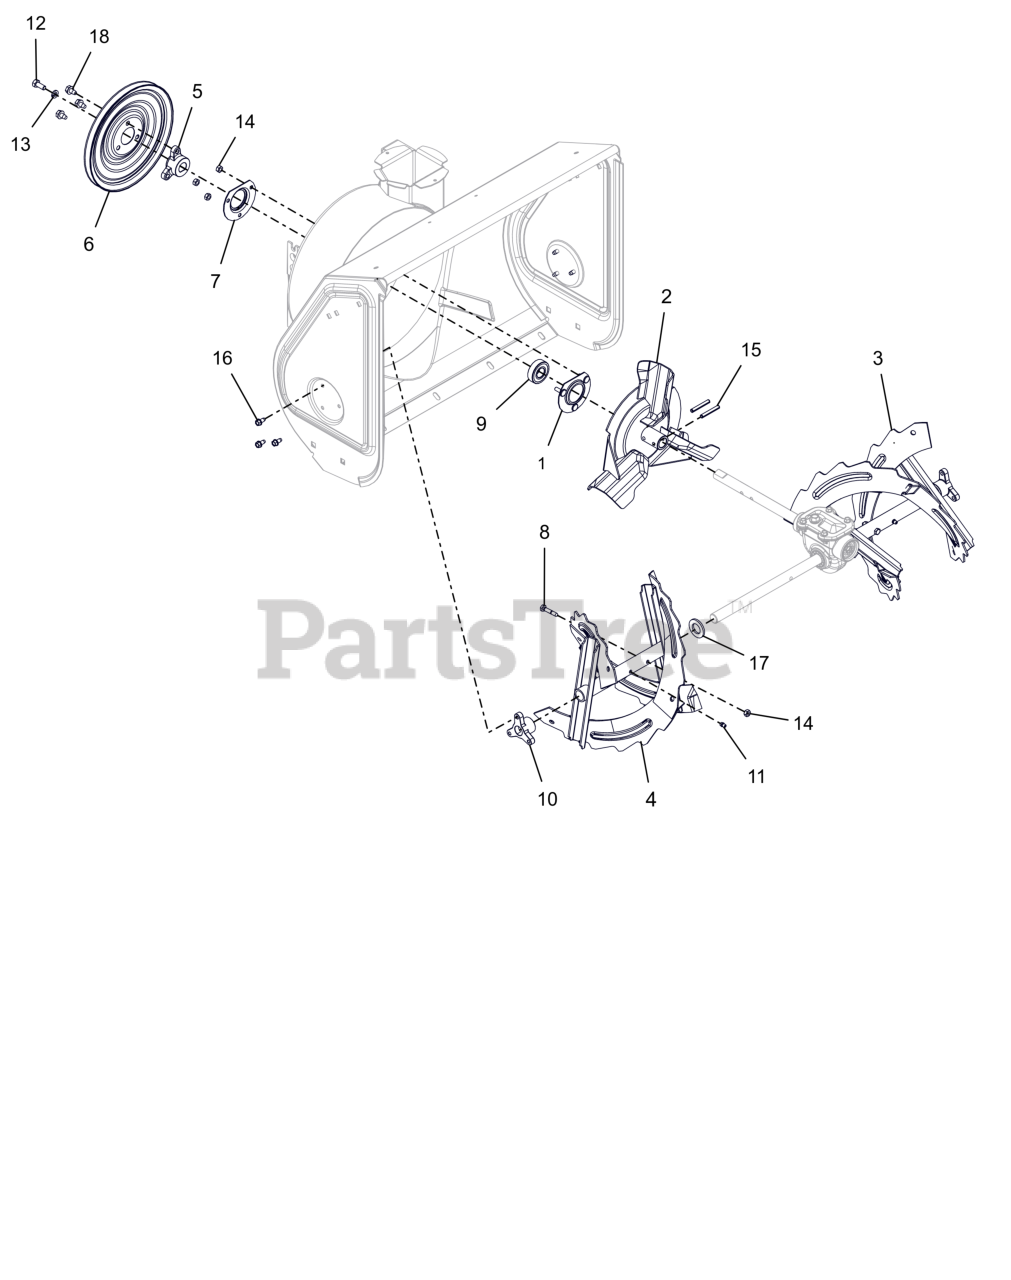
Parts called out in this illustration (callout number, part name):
1	BEARING FLANGE
2	IMPELLER, COMPACT 12" 3-BLADE
3	RAKE, 24" LH, BLK SERR W/ZERK
4	RAKE, 24" RH, BLK SERR W/ZERK
5	PULLEY HUB, BOLT-ON D-BORE .75
6	PULLEY,SPIN FORM SINGLE GROOVE
7	BEARING FLANGE
8	SHEAR BOLT
9	BRG-BALL .750X1.750X.50
10	BUSHING, RAKE SHAFT .75"
11	ZERK,FITTING .25X.125 DRIVE IN
12	BLT, HEX .31-24X.750 G5 ZCC
13	WSHR, LK-HVY .312X.097 ZCC
14	NUT,LK-CTR .25-20 GA ZCC
15	PIN-ROLL .250X1.75
16	SCR-TAP .25-20X.50 HWH ZCC
17	WSHR, FLT .812X1.469X.134 ZCC
18	SCR,TAP .312-18X.50 HWH TR ZCC
